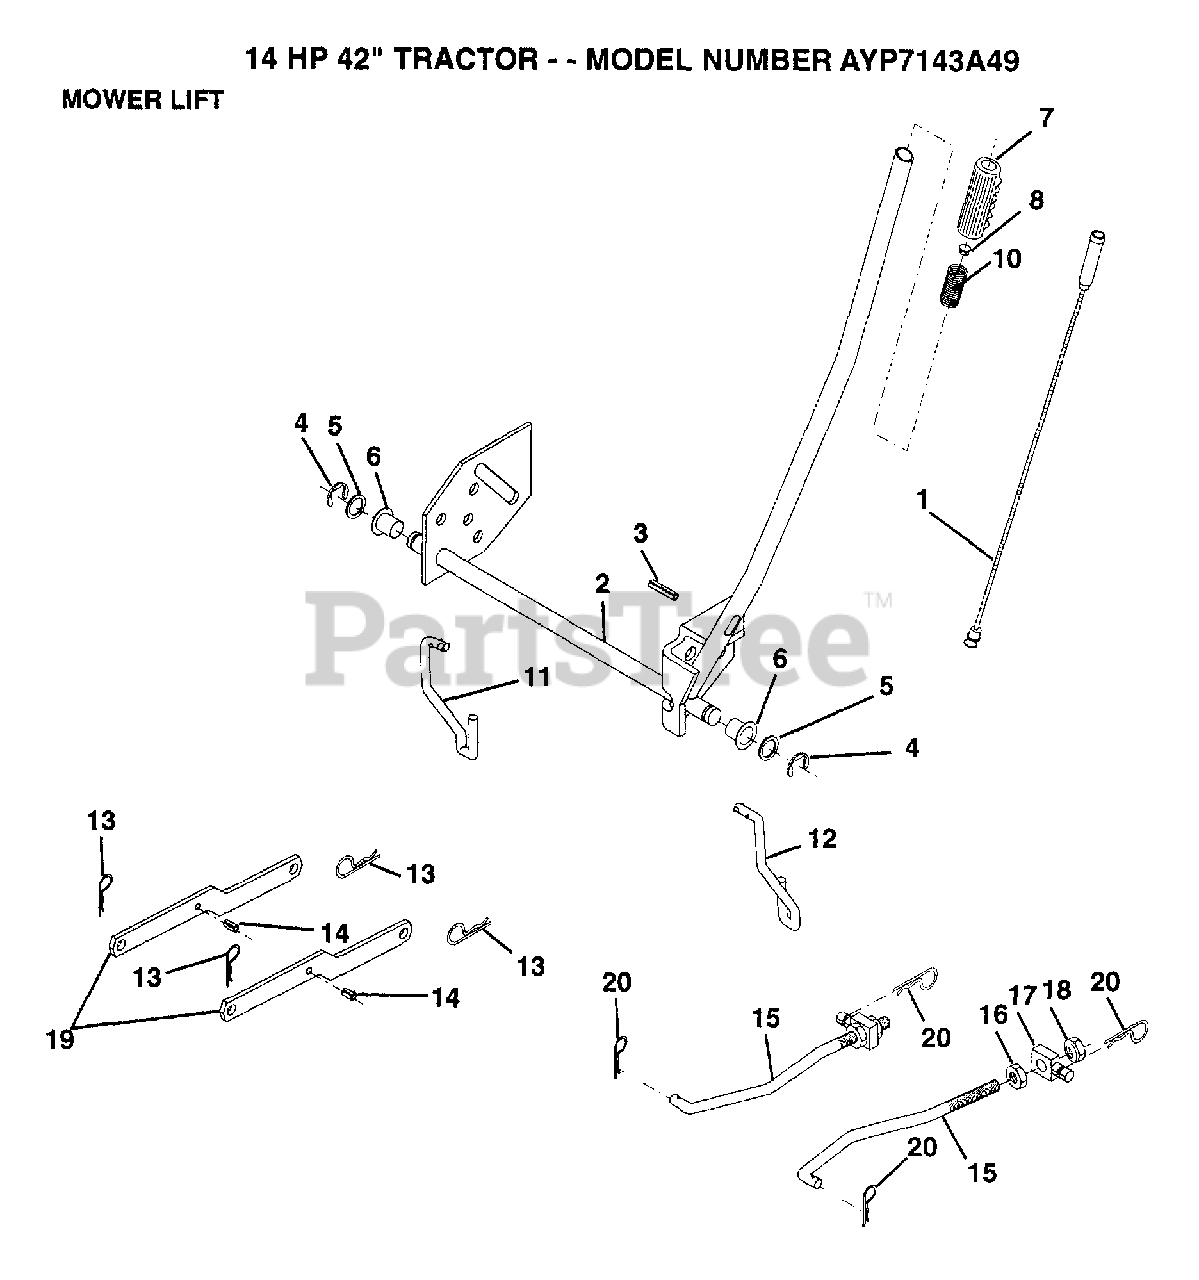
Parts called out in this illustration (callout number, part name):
1	WIRE ASM
3	PIN-GROOVE LT
5	WASHER
6	NYLON BEARING
7	GRIP
11	LINK LIFT LH
12	LIFT LINK RH
14	"PIN,SPRING"
15	LINK.FRONT
16	NUT
17	TRUNION
18	NUT.LK.W/WSH.1/2.
20	RETAINER.SPRING
